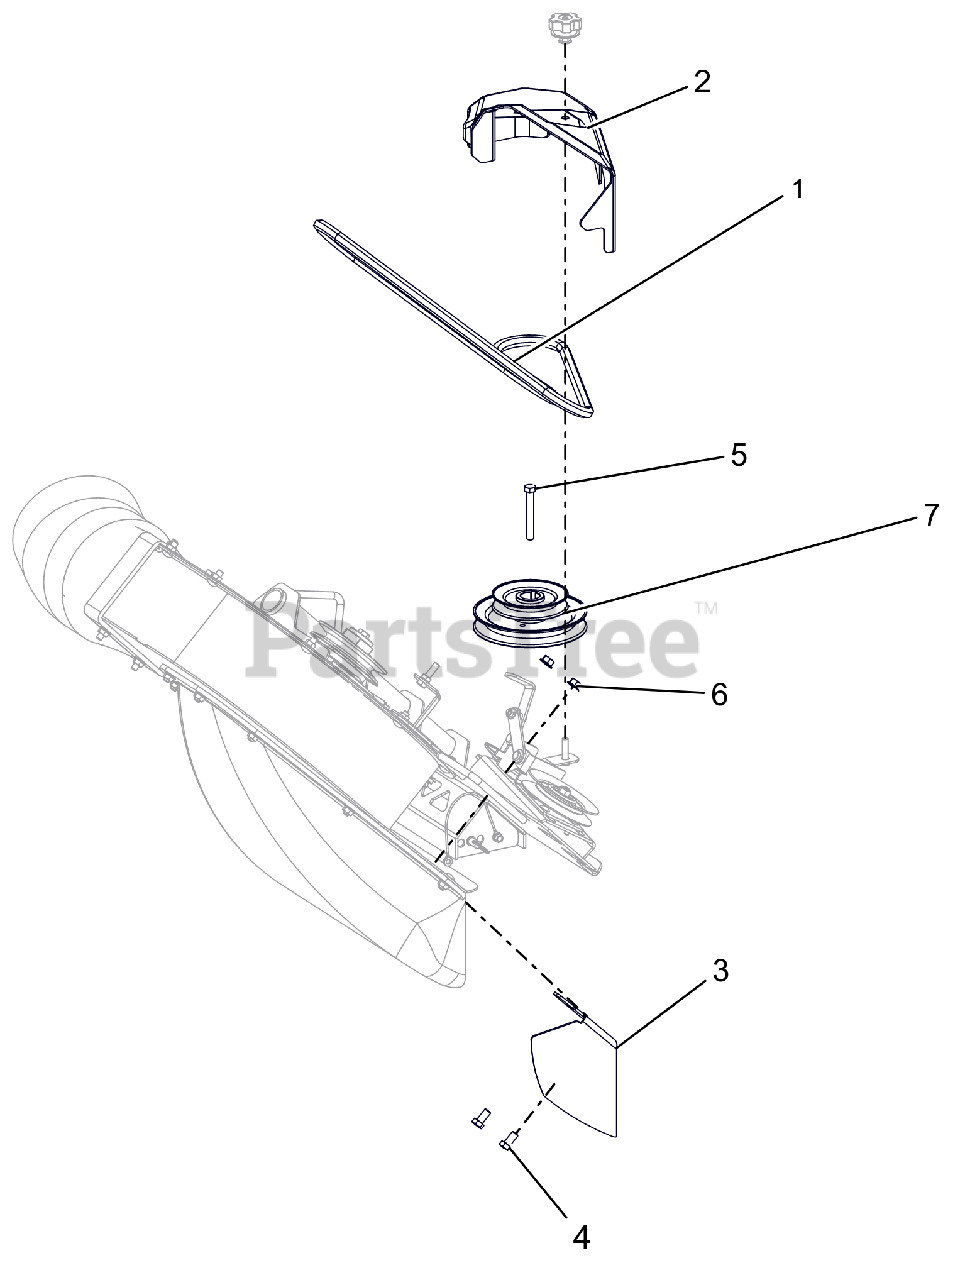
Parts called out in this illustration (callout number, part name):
1	HEX BELT, AA-WRAPPED
2	COVER, BELT 44-48 BLOWER
3	BAFFLE, BOLT-IN 44-48 BLOWER
4	@BLT-HEX .38-16X.75 GR5 YWZC
5	BLT-HEX .38-16X2.75 GR8 YWZC
6	@NUT-LK-TOP-FLG .38-16 YWZC
7	PULLEY, V-1.00"IDX4.50"OD LFB
